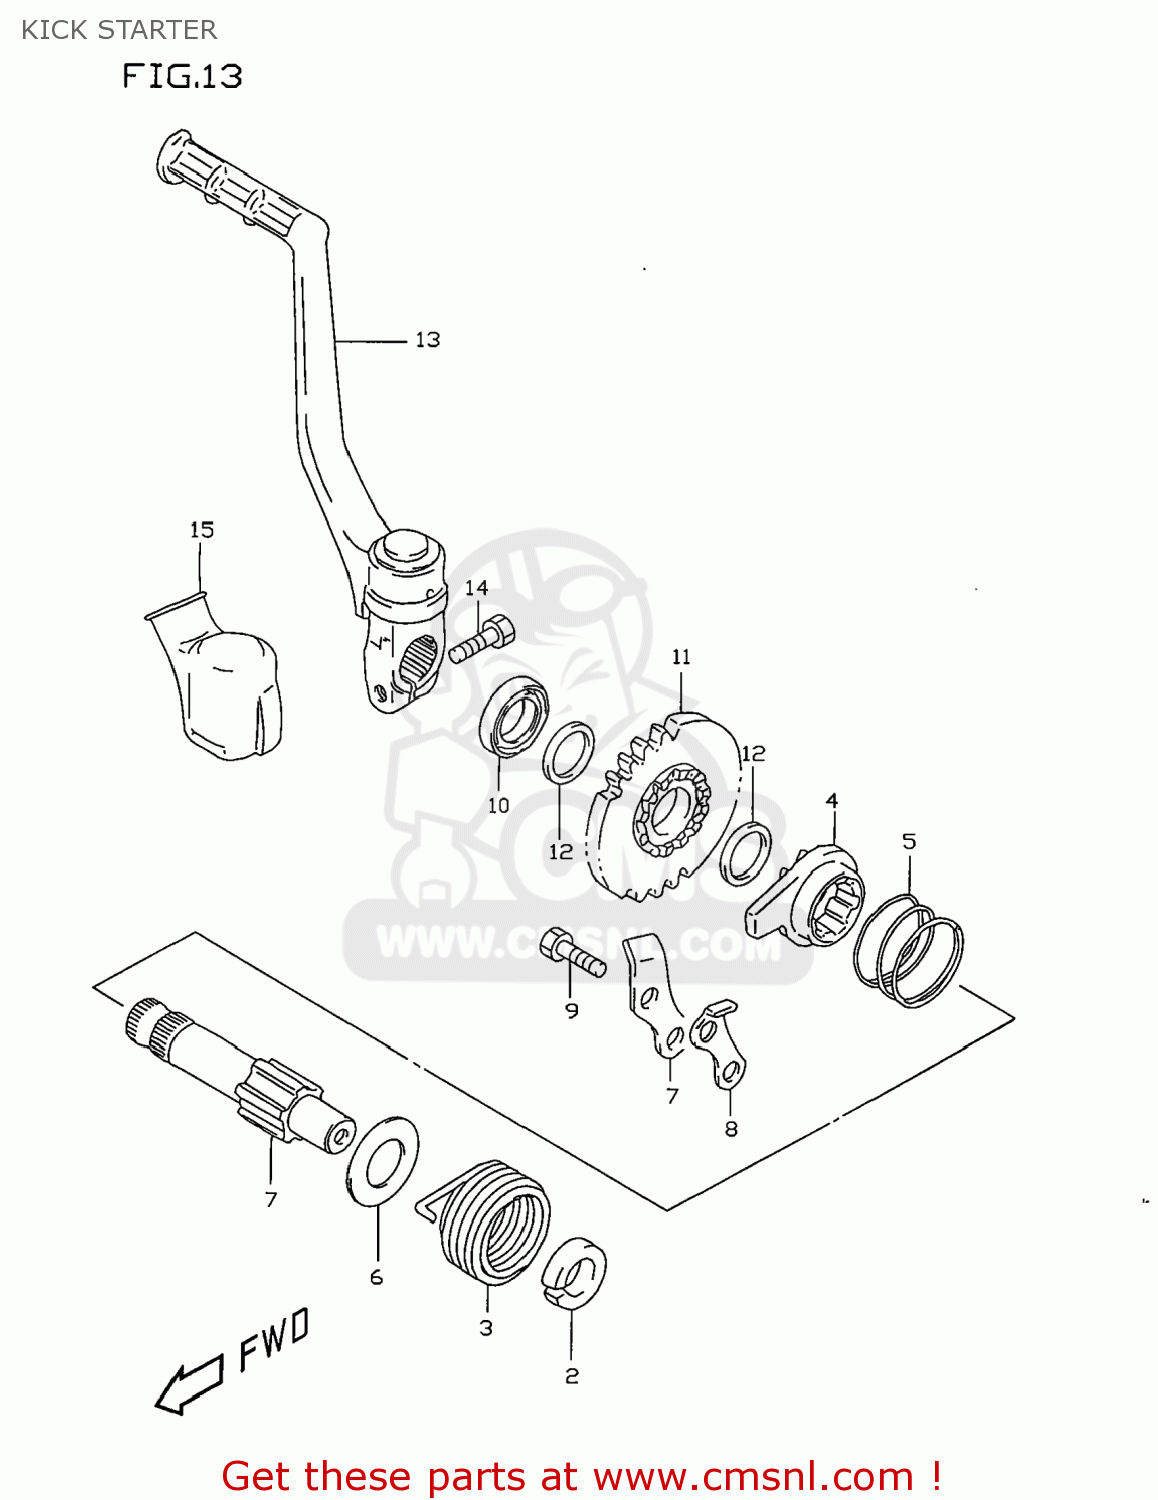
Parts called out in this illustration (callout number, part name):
1	SHAFT,KICK STARTER
2	GUIDE,SPRING
3	SPRING
4	STARTER,KICK
5	SPRING
6	WASHER
7	GUIDE,KICK STARTER
8	STOPPER,KICK STARTER
9	BOLT
10	SEAL,OIL(14X24X6)
11	GEAR,KICK STARTER DRIVE
12	WASHER
13	LEVER ASSY,KICK STARTER
14	BOLT
15	COVER,KICK LEVER JOINT
